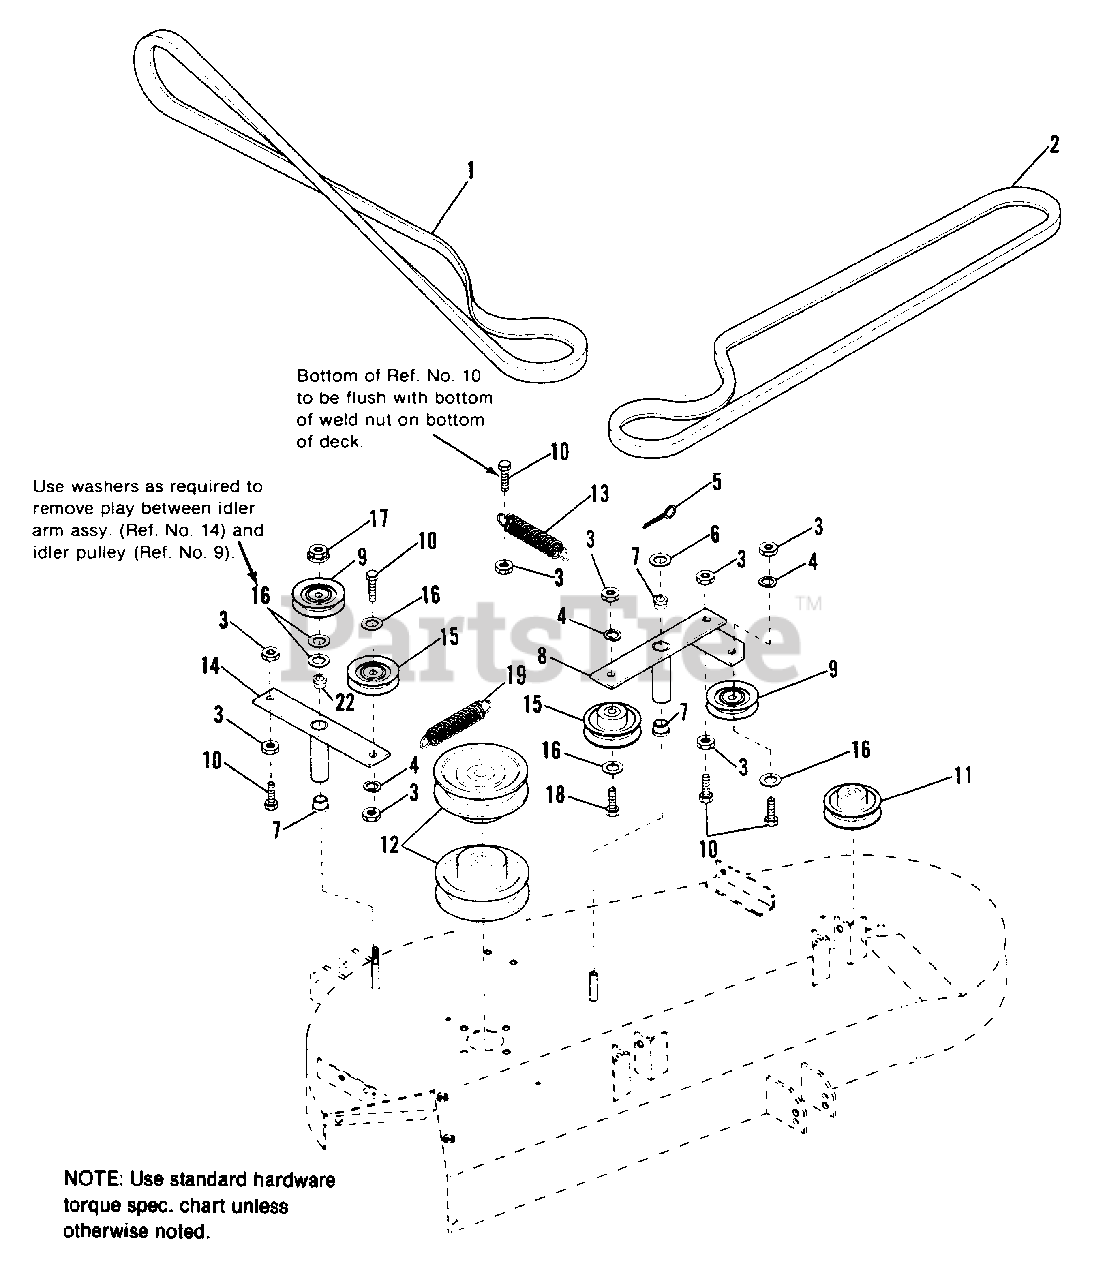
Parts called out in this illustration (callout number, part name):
1	V-BELT, Mower
2	V-BELT, Mower
3	NUT, Hex, 3/8-16
4	LOCKWASHER, Spring, 3/8
6	WASHER, Plain
7	BEARING, Nylon, Flanged
8	MOWER IDLER ARM ASSY.
9	V-PULLEY, Idler, 3" dia.
10	CAPSCREW, Hex, 3/8-16 x 1-1/2
11	V-PULLEY, Drive
12	V-PULLEY, Drive
13	SPRING, Extension
14	IDLER ARM ASSY.
15	PULLEY, Idler, Backside 3-1/2" dia.
16	WASHER, Plain
17	NUT, Lock, Hex, Flanged, 3/8-16
18	CAPSCREW, Hex, 3/8-16 x 1-3/4
19	SPRING, Tension
